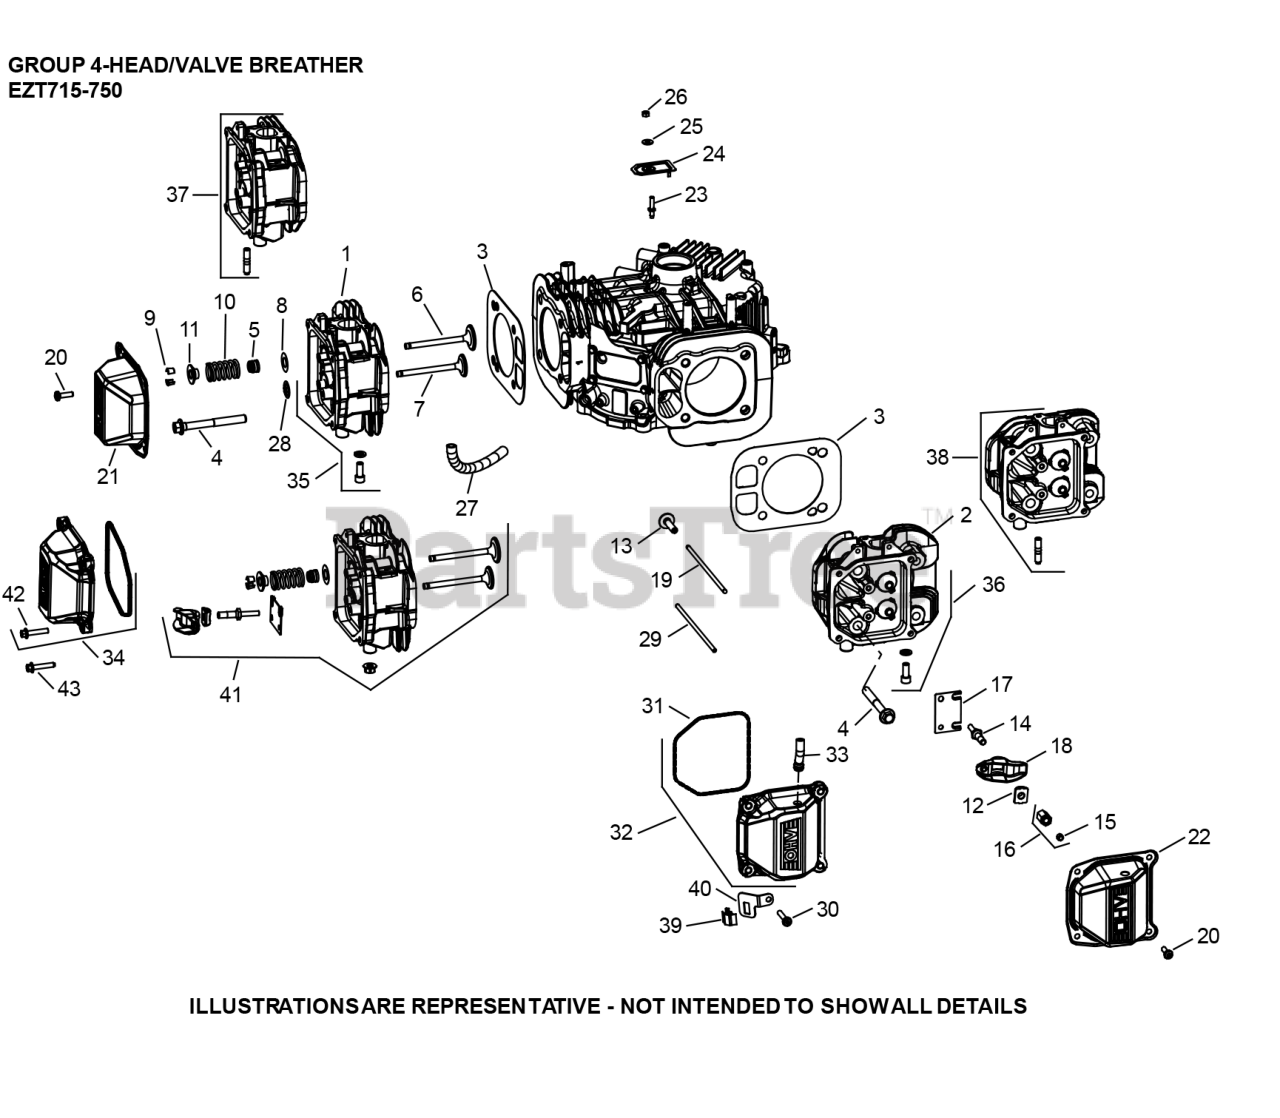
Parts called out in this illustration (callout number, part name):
1	CYLINDER HEAD KIT #1
2	CYLINDER HEAD KIT #2
3	GASKET KIT-CYL HEA
4	HEX SCREW FLG M10X
5	VALVE STEM SEAL
6	INTAKE VALVE .25
7	EXHAUST VALVE
7	EXHAUST VALVE .25
9	KIT-RETAINER
11	VALVE CAP SPRING
12	PIVOT- ROCKER ARM
13	TAPPET-PUSH ROD
16	NUT ASSEMBLY-ROCKER
20	PAN HEAD SCREW
21	COVER-ROCKER #2 CYL
23	STUD-BRETHR REED C
24	COVER-BREATHER REED
25	SEALING WASHER
27	BREATHER HOSE
28	VALVE GUIDE RETAINER
